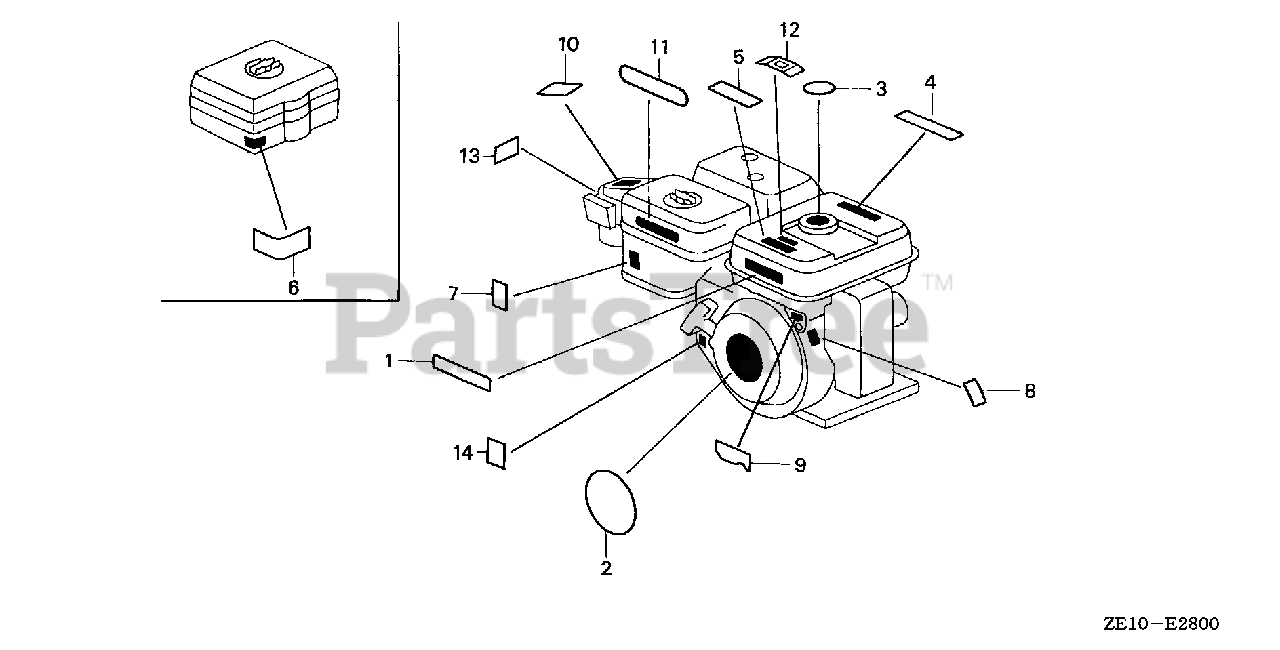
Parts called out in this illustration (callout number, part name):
2	EMBLEM (EXTERNAL)
3	MARK, CAUTION
7	MARK, CHOKE
